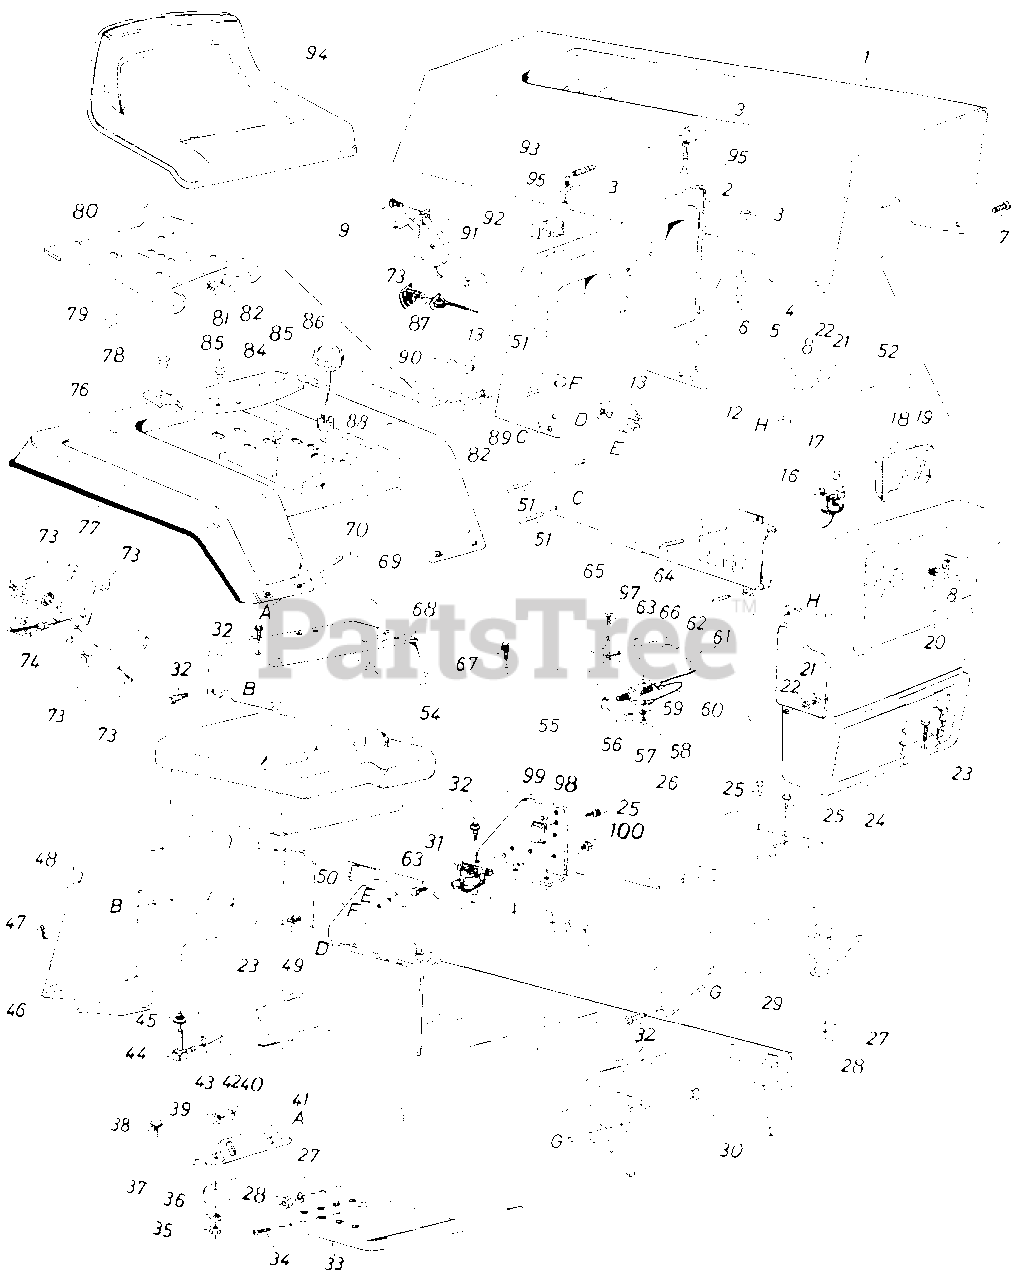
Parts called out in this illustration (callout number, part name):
1	Hood
2	Trim Strip-27" Lg.
3	Fl-Wash. .20" I.D. x .41" O.D.
5	Hood Stop
6	Truss Hd. Mach. Scr. #10-24 x .50" Lg.
7	Hex Bolt 1/4-20 x .62" Lg.
8	Fl-Wash. 1/4" I.D.*
9	Truss Mach. AB-Tap Scr. #10 x .50" Lg.
12	Dash Ass'y.
13	Ignition Switch
16	Socket
17	Lamp
18	Headlight Housing
19	Lens
20	Hex L-Nut 1/4-20 Thd.
21	Hex Nut 1/4-20 Thd.
22	L-Wash. 1/4" I.D.*
23	Hex Bolt 5/16-18 x .75" Lg.*
24	Grille
25	Hex Wash. Hd. Scr. 1/4" x .50" Lg.
26	Battery Plate
27	L-Wash. 5/16" I.D.
28	Hex Nut 5/16-18 Thd.*
29	Grille Mounting Bracket
30	Lower Frame Ass'y.
31	Solenoid
32	Hex Thd. Rolling Scr. 5/16-24 x .75" Lg.
33	Running Board-R.H.
34	Truss Mach. Scr. 5/16-18 x .75" Lg.
35	Hex Nut 5/16-18 Thd.*
36	Bell-Wash. .34" I.D. x .87" O.D.
39	Hex Nut 1/4-20 Thd.
40	L-Wash. 1/4" I.D.*
41	Running Board Rod
42	Fuel Line 40" Lg.
43	Hose Clamp 3/8"
44	90ø Nipple
45	Bushing
46	Hitch Rod
47	Internal Cotterpin
48	Hitch Plate
49	Speed Nut
50	Dash Support Brkt.-R.H.
51	Hex Wash. Hd. Tap Scr. 1/4 x .75" Lg.
52	Tie Strap
54	Fuel Tank
55	Transmission Cover Ass'y.
56	Switch Actuator Spring Lever
57	Safety Switch
58	Hex Nut 1/4-20 Thd.*
59	L-Wash. 1/4" I.D.*
60	Electric Wire
61	Reverse Lockout Wire Harness
62	Snap Bushing
63	Hex Bolt 1/4-20 x .50" Lg.*
64	Truss Hd. Scr. 1/4-20 x .75" Lg.*
65	Side Panel-R.H.
66	Truss Mach. Scr. 1/4-20 x .50" Lg.*
67	Truss Mach. "B" Tap Scr. #10 x .50" Lg.
68	Seat Mounting Channel
69	Carriage Bolt 1/4-20 x .50" Lg.*
70	Seat Bracket-R.H.
73	Throttle Control Box Ass'y.
74	Throttle Control Wire
78	Grommet
79	Hex Wash. Hd. AB-Tap Scr. 318 x .75" Lg.
80	Seat Pivot Bracket
81	Hex Cent. L-Nut 5/16-18 Thd.
82	Belleville Wash. .34" I.D. x .88" O.D.
84	Seat Spring
85	Hex Wash. Hd. Self-Tap Scr. 5/16-18 x .50" Lg.
86	Gas Cap w/Gauge
87	Choke Control Comp.
88	Seat Bracket-L.H.
89	Hex Bolt 5/16-18 x .75" Lg.*
90	Ignition Key
91	Light Switch
92	Ammeter
93	Hood Spring
94	Seat Ass'y.
95	Hex Screw #10-24 x 1.0" Lg.*
97	Rubber Strip 1/2" Sq. x 21/2" Lg.
98	Circuit Breaker
99	Dash Support Brkt.-L.H.
100	Hex Sems Nut 1/4-20 Thd.
